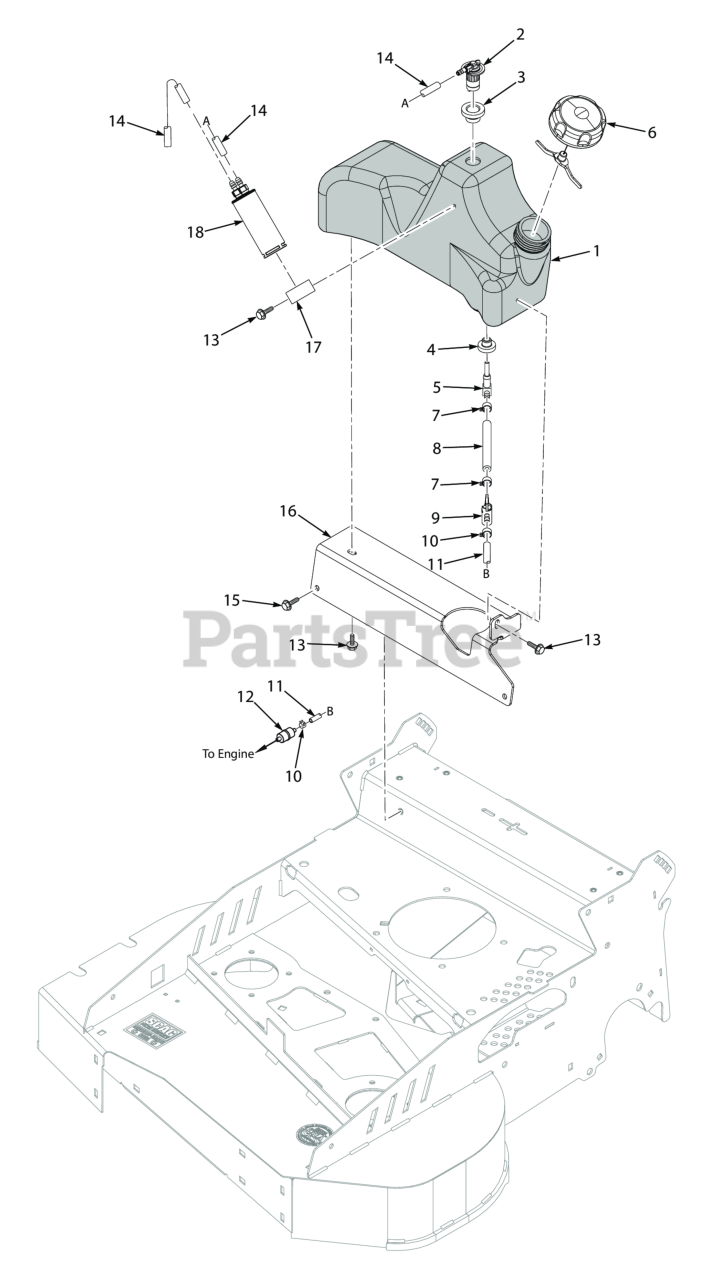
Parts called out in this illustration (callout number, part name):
1	Fuel Tank Assembly w/Decal (incl. #2, #3, #4, #5)
2	Valve
3	Grommet, Valve
4	Bushing, 0.56" Dia. Viton
5	Elbow, 90 Degree w/Screen
6	Cap, Fuel Tank
7	Clamp, Fuel Hose 1/4" Hose I.D.
8	Fuel Hose, 1/4" I.D. Non-Perm (791DFI Fuel Return) - Order by Inch
9	Valve, Fuel Shutoff
10	Clamp
11	Fuel Hose
12	Fuel Filter
13	CAP SCREW, 1/4-20 X 1/2" SERRATED FLANGE HEX
14	Hose, Vapor Recovery 3/16" (order by inch)
15	CAP SCREW, 1/4-20 X 1/2" SERRATED FLANGE HEX
16	Bracket, Fuel Tank
17	Clamp, 1-1/2" Cable
18	Canister, Carbon 1.28 Gal.
